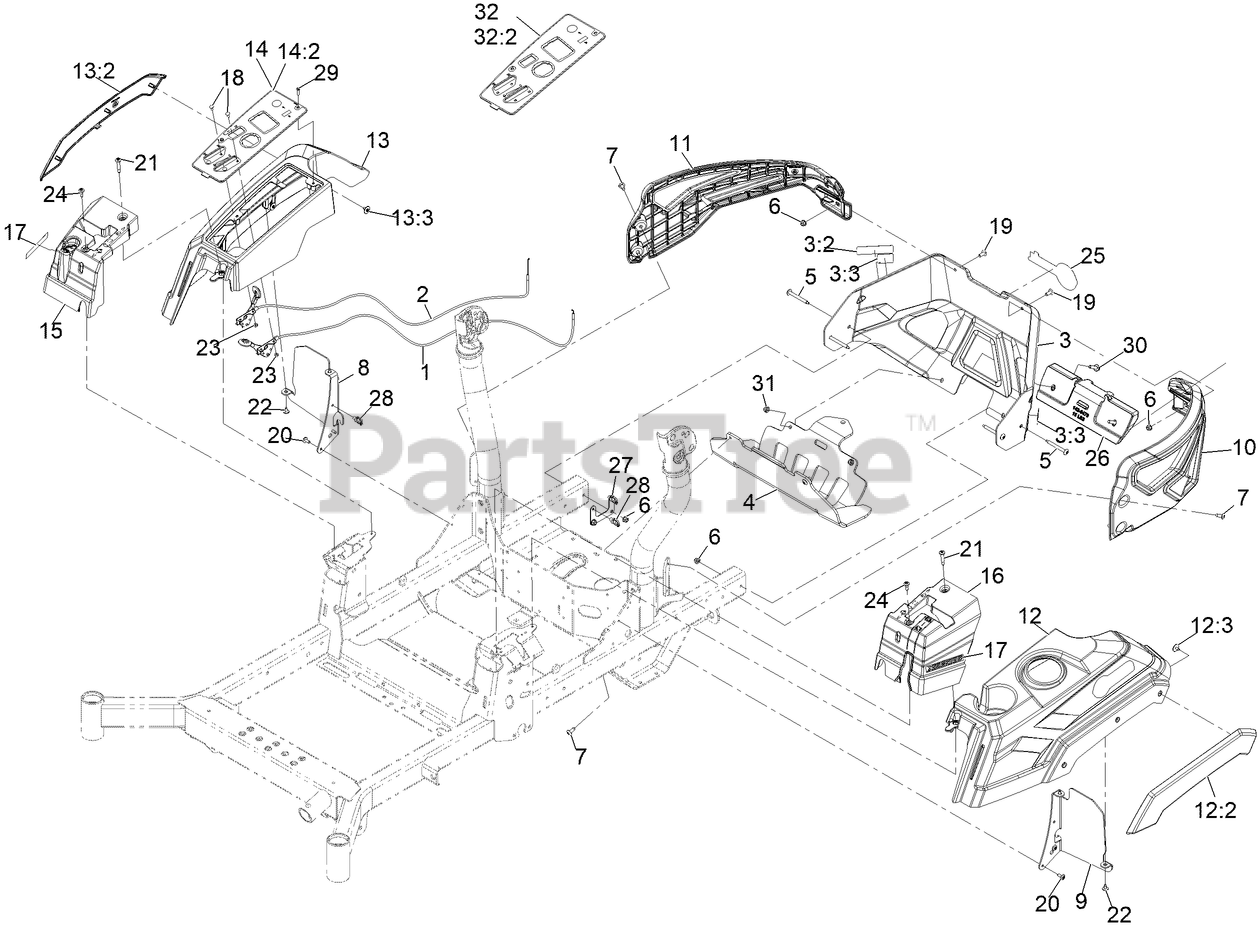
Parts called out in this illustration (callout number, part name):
1	CABLE, THROTTLE CONTROL
2	ASM,CHOKE CABLE
3	ASM, Rear Guard W/ Decals
3:2	DECAL-ARRESTOR, SPARK
3:3	DECAL-WARNING
4	GUARD, MUFFLER [BLACK]
5	SCREW-TORX
6	NUT-HF, NI
7	SCREW, TAPTITE
8	Bracket, Pod, Rt
9	Bracket, Pod, Lt
10	GUARD, UPPER, LT
11	GUARD, UPPER, RT
12	ASM, Pod Lt
12:2	Fender, Lt
12:3	Screw-Torx
13	ASM, POD RT
13:2	Fender, Rt
13:3	Screw-Torx
14	ASM-Control Panel W/Decal
14:2	DECAL-CONTROL PANEL
15	Cover, Motion Control, Rt
16	Cover, Motion Control, Lt
17	DECAL-X-SERIES
18	BOLT-CARR
19	SCREW-TORX
20	SCREW-TORX
21	SCREW-SHOULDER
22	SCREW-TORX
23	NUT-LOCK, NI
24	SCREW-SHOULDER
25	DECAL, EXMARK LOGO
26	WEIGHT, REAR
27	BRACKET, CABLE MOUNT
28	CLIP-TIE
29	Screw-Plastic, HWH
30	SCREW-HHF
32	ASM-Control Panel W/Decal
32:2	Decal-Control Panel
